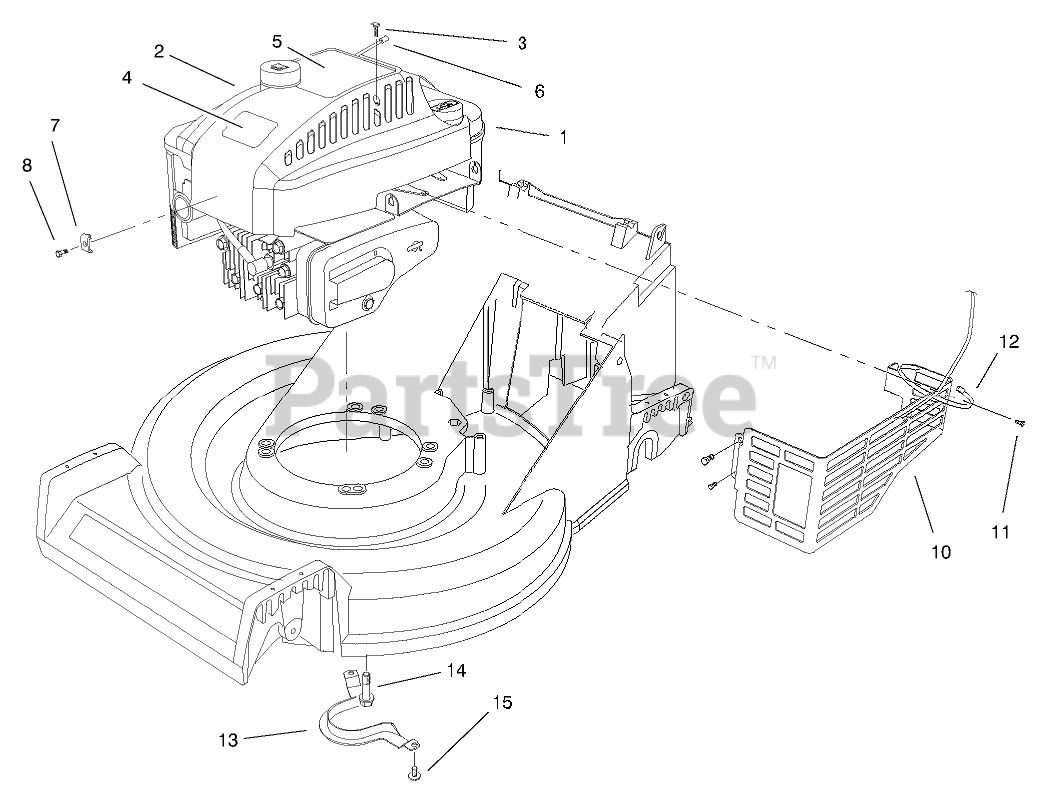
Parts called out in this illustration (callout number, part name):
2	SHROUD-ENGINE
3	SCREW-PPH
4	Decal
5	DECAL - RECOIL
6	STOP-ROPE
7	CLAMP-CASING
8	SCREW-CLAMP
10	SHIELD-MUFFLER
11	SCREW-HWH
12	TIE-CABLE
13	Guide-Belt
14	SCREW-HWH
15	SCREW-HWHTF
